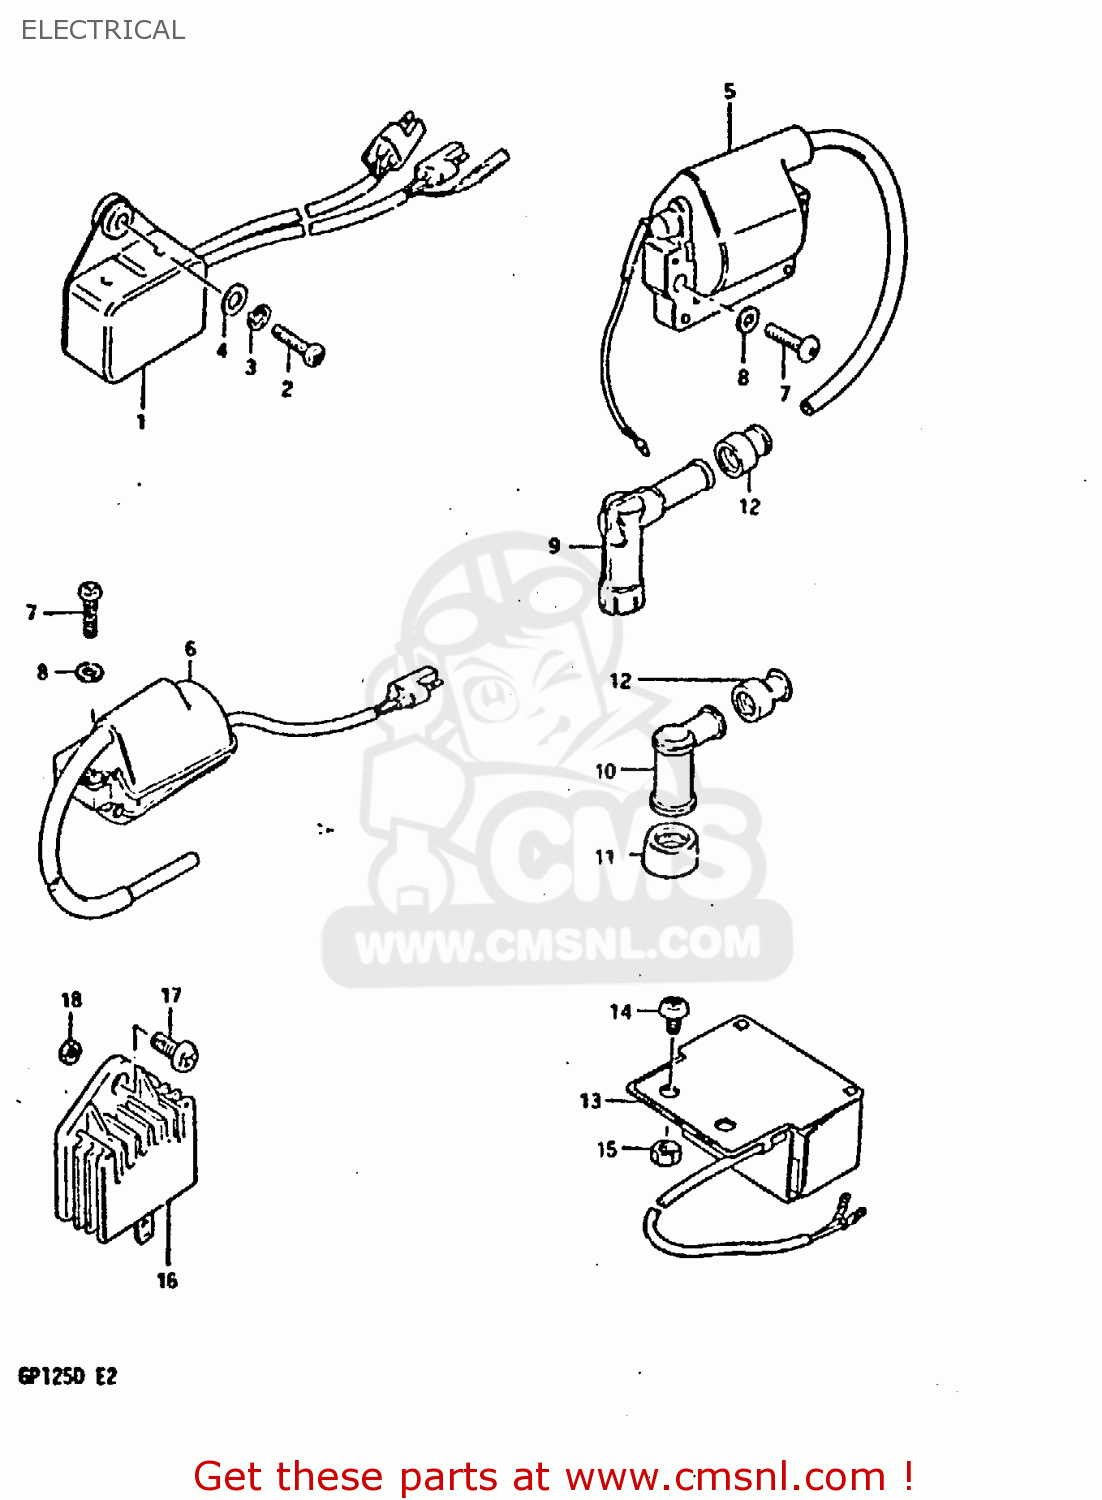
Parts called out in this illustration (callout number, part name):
5	COIL ASSEMBLY,IGNITION
7	SCREW 5X20
8	WASHER
9	CAP,SPARK PLUG
12	SEAL,SPARK PLU
13	RESISTOR ASSY
14	SCREW
15	NUT
